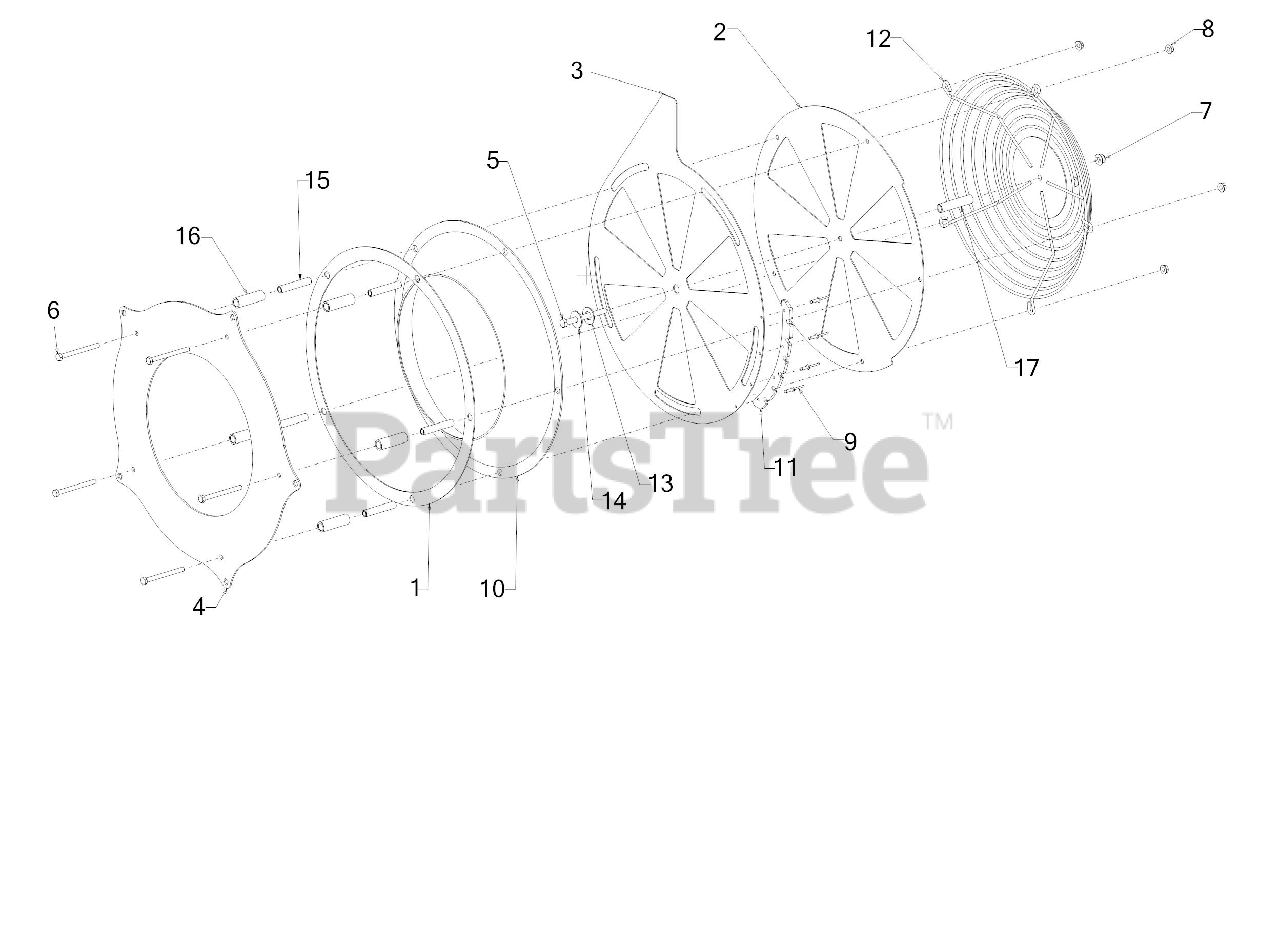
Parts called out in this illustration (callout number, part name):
1	BELL SUPPORT RING
2	BLOWER STATIC IRIS INTAKE PLATE
3	BLOWER IRIS INTAKE PLATE
4	BLOWER MOUNT INTAKE PLATE
5	SCREW 3/8-16 x 3.75 GR5
6	SCREW 5/16-18X3.5 GR5
8	FLANGE NUT
9	POP RIVET .187 DIA
10	BLOWER INLET BELL
11	BLOWER IRIS RING GEAR
12	BLOWER INTAKE GRILL
13	FLAT WASHER NYLON 5/8
14	SHOULDER SPACER
15	SPACER .5 X .334 X 2.75
16	TUBE SPACER .75 X .525 X 2.375
17	SPACER .625 X 4.06 X 2.87
